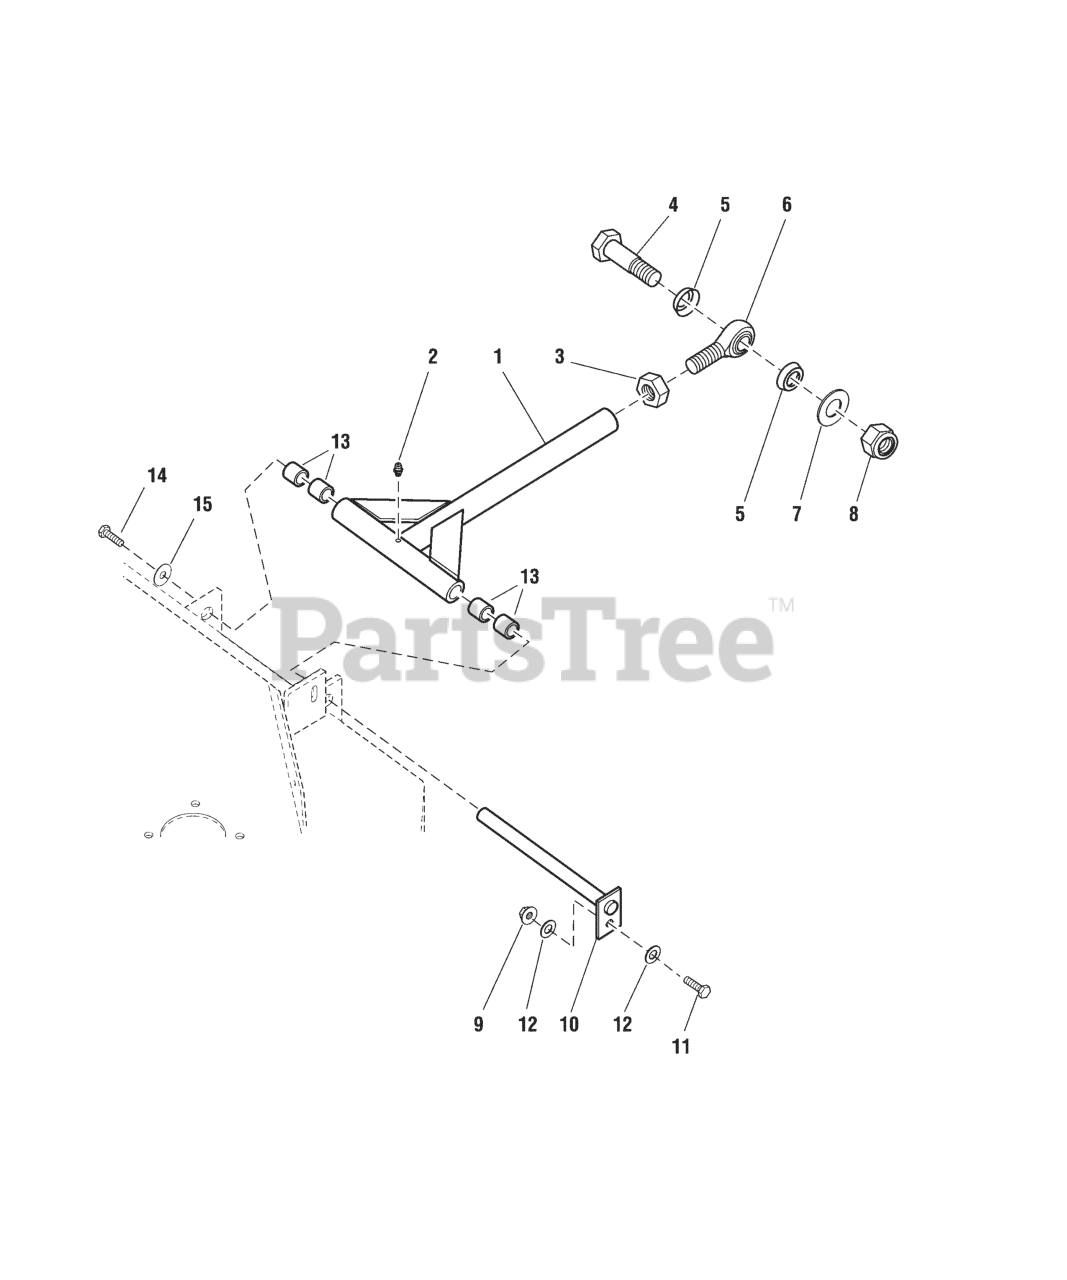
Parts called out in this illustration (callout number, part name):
1	ASSM, DECK PUSHER BAR
2	GREASE FITTING
3	NUT, 3/4-16 Hex Jam
4	BOLT, 3/4-16 x 3
5	ROD END SEAL
6	BALL JOINT, 3/4-16 Male
7	WASHER, 3/4 SAE
8	NUT, 3/4-16 Hex Nylon Lock
9	NUT, 3/8-16 HEX NYLON LOCK
11	BOLT, 3/8-16 X 1-1/4" GD5 CZ
12	WASHER, 3/8 SAE
13	BUSHING, .75 X 1.00 X 1.00, PLASTIC
14	BOLT, 3/8-16 X 1" GD5 CZ
15	WASHER, .390 X 1.50 X .109 YZ
